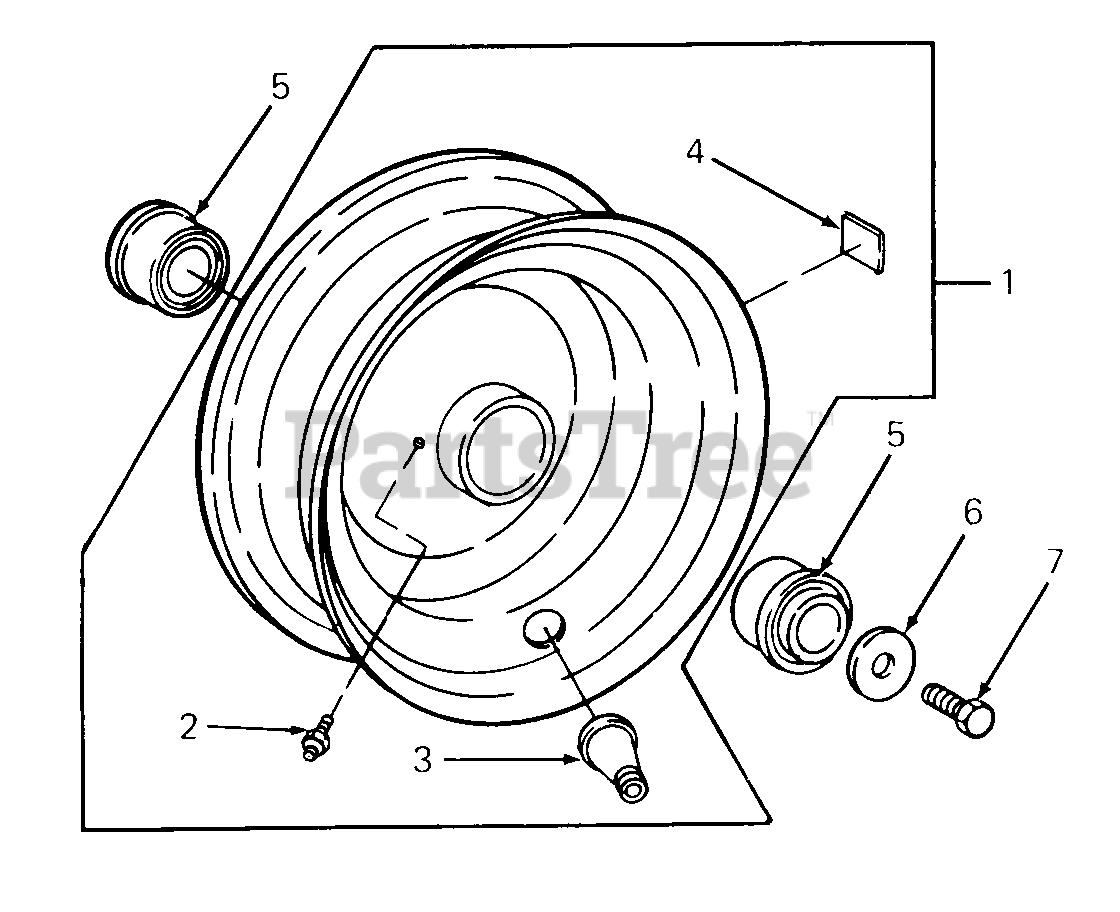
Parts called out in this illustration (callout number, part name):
1	Wheel Assy, Front
2	Fitting, Lube
3	Valve, Tubeless Air
4	Label, Inflation
5	Bearing, Wheel Ball
6	Washer, Flat, .406 X 1.75 X .105 Thk
7	Screw, Hex Cap, 3/8-16 X.75 Lg GR5
